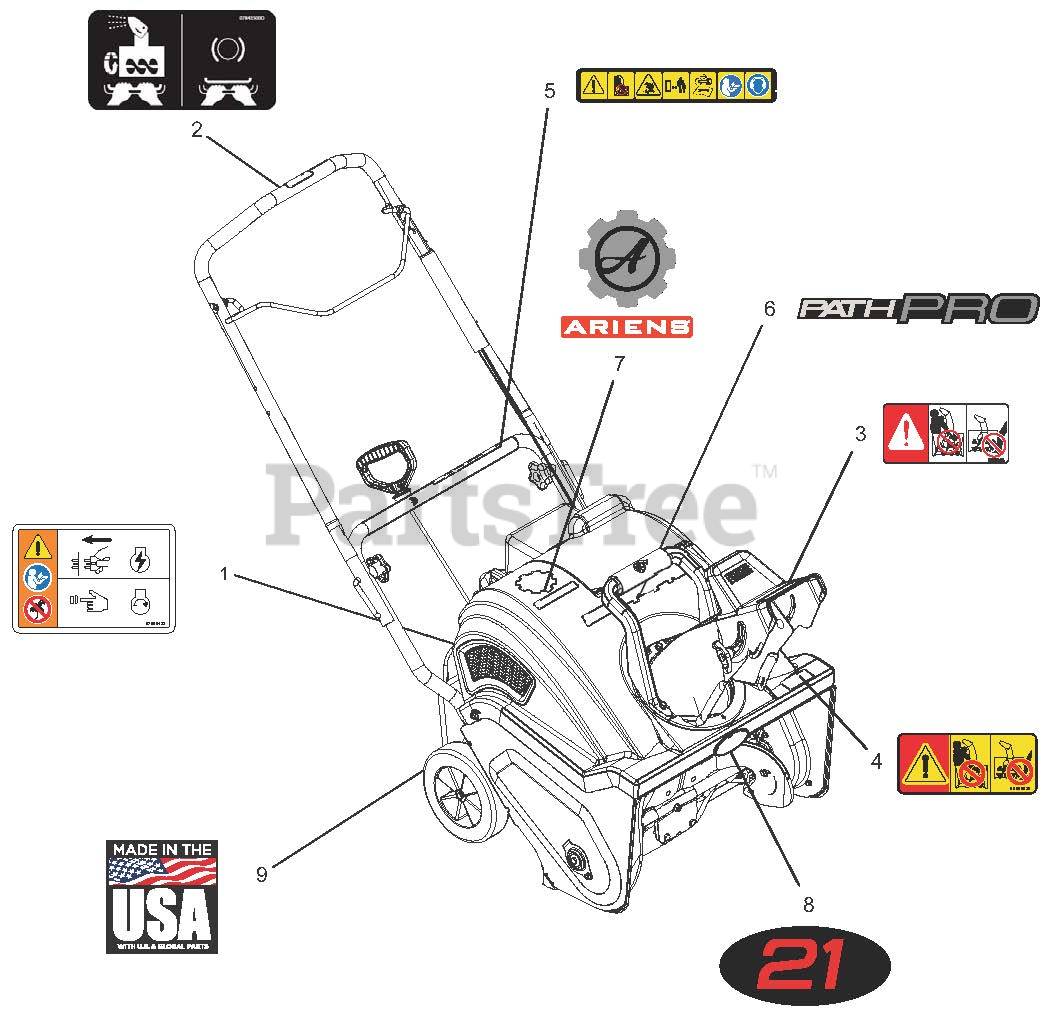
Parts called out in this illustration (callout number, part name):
1	DECAL, ELECTRIC START
2	DECAL-AUGER/IMPELLER BAIL
3	DECAL, DANGER
4	DECAL, DANGER SINGLE STAGE
5	DECAL, WARNING
6	DECAL, COWL - PATHPRO
7	DECAL, ARIENS GEAR/BRAND, SS
8	DECAL, COWL - PATHPRO 21
9	DECAL, MADE IN USA
